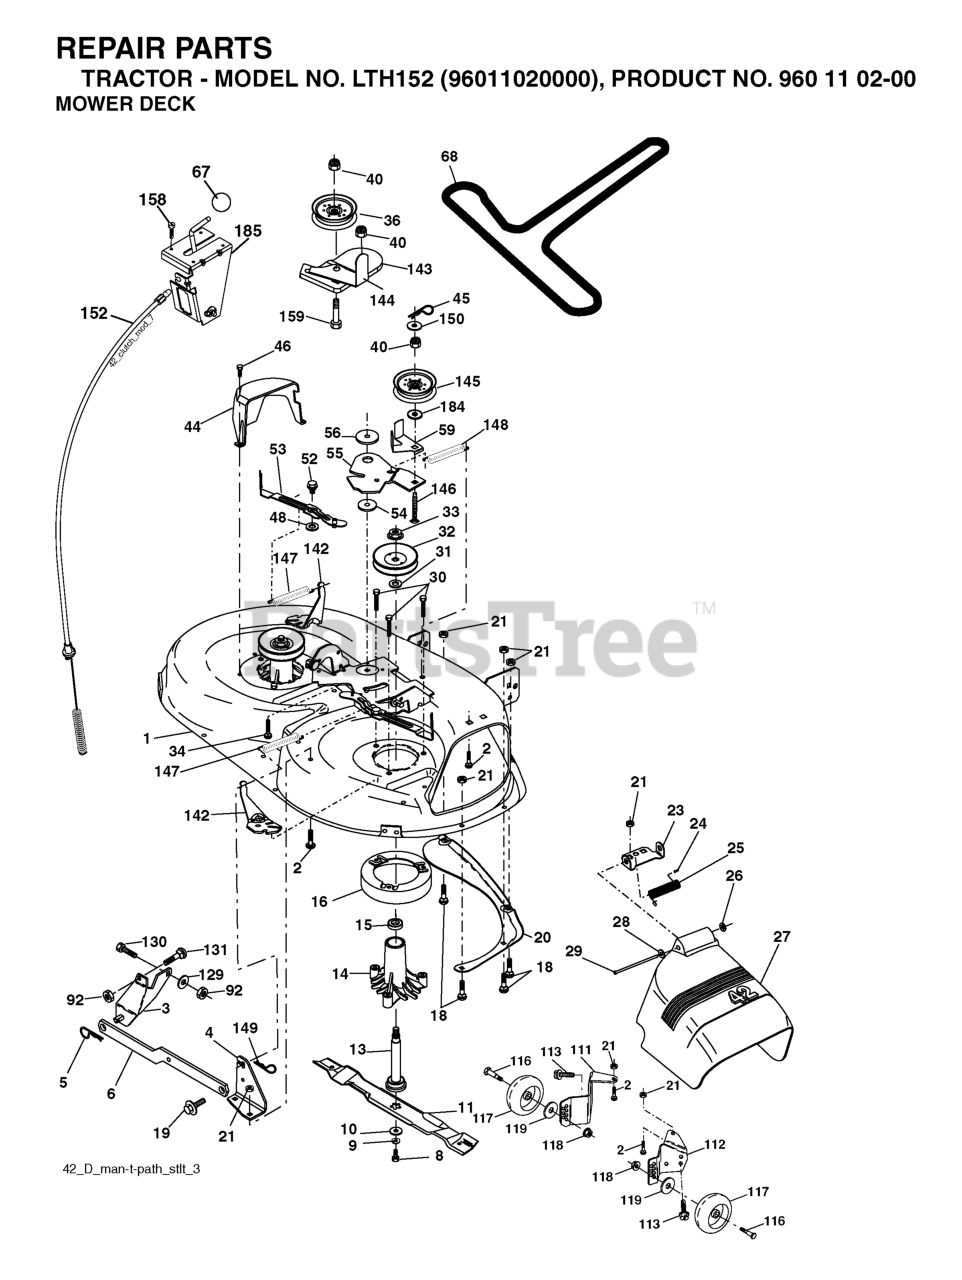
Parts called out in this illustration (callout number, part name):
1	42" DECK KIT
2	RP BOLT 5/16-18 X3/4 ZN/YEL GR
3	BRKT ASM SWAY BAR
4	BRACKET SWAY BAR 42" DECK
5	RETAINER-SPRNG RB
6	BAR SWAY DECK
8	BLADE BOLT
9	LOCKWASHER
10	WASHER.BLADE
11	42" HI-LIFT BLADE
13	SHAFT ASM VENT
14	HOUSING.MANDREL.VENTED (MACHD)
16	STRIPPER.MANDREL.ROUND.BLACK
18	BOLT
19	BOLT SHD 5/16-18
20	BAFFLE.VORTEX
21	LOCKNUT
23	BRKT, DEFL. MOWER
24	CAP-SLEEVE LT
25	SPRING TORSION
26	NUT PUSH M
27	SHIELD DEFLECTOR
28	Washer 11/32 x 5/8 x 16 Ga SD
29	ROD.HINGE
30	SCREW, WASHER HEAD
31	WASHER.SPACER.MANDREL
32	PULLEY/MANDREL
33	NUT.FLANGE.LOCK.TOP
34	BOLT.3/8-16X1.50
36	FLAT IDLER PULLEY
40	NUT LOCK FLG 3/8-16 UNC
44	GUARD MANDREL LH BLACK
45	RETAINER M
46	SCREW.1/4-20X5/8
52	BOLT.SHOULDER.5/16-18
53	ARM BRAKE ASSY
55	ARM IDLER 42" MOWER LT/YT
56	SPACER.RETAINER.MOWER
59	GUARD, BELT
67	KNOB T (3/8 HOLE)
92	NUT
111	BRACKET, WHEEL
112	BRACKET, WHEEL
113	BOLT.5/16HEX.WHS.HD
116	BOLT M
117	WHEEL.GAGE.HALF.SPOKED
118	LOCKNUT
119	WASHER.5/16.FLAT.STE.STD.
129	WASHER
131	BOLT D
142	ARM SPRING BRAKE MOWER
143	BRACKET, ARM IDLER
144	DNO KEEPER.BELT.42".CLUTCH.CBL
145	PULLEY
146	BOLT, CARRIAGE IDLER BLACK
148	IDLER RETURN SPRING
149	SPRING.RETAINER.YELLOW.ZINC
152	CABLE.CLUTCH.42"
158	SCREW
184	WASHER
185	HEAD ASM. CABLE CLUTCH
